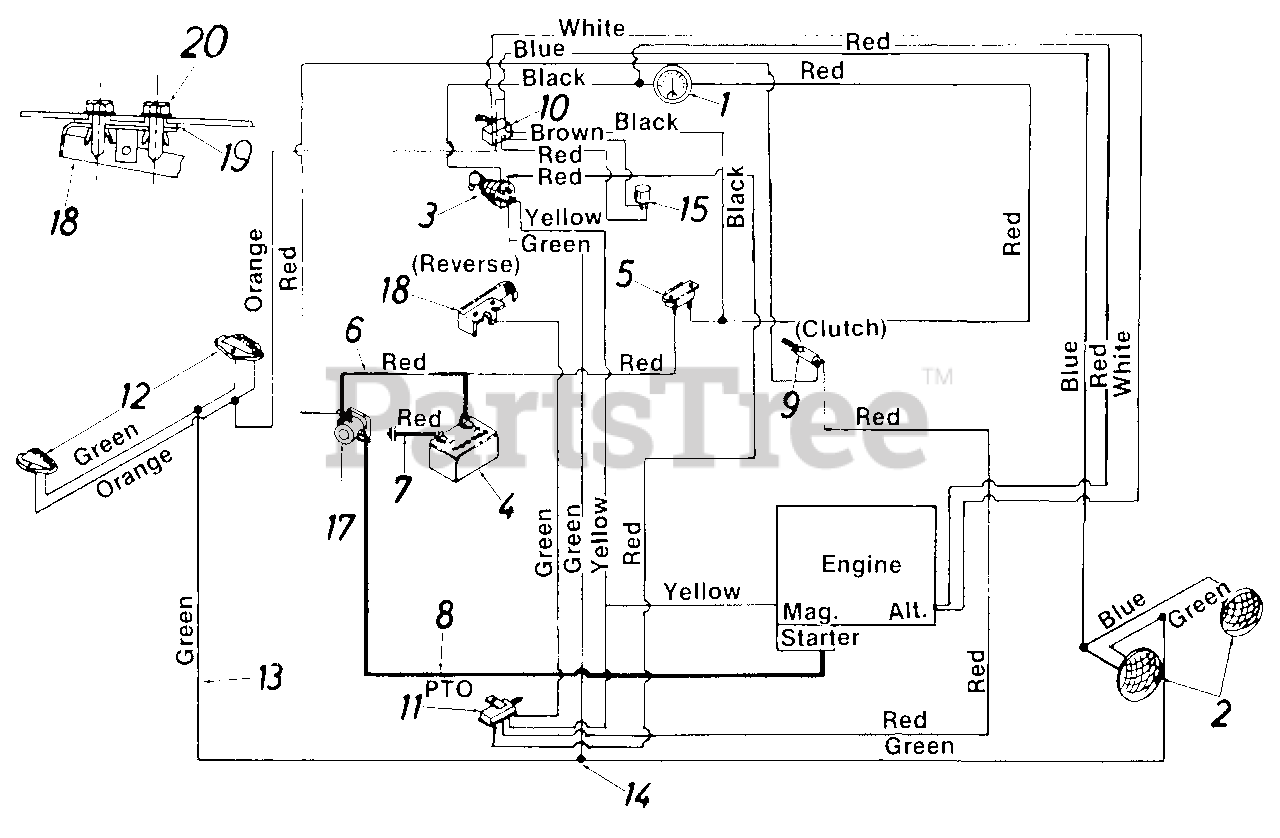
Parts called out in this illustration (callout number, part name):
1	Ammeter
2	HeadLight
3	Ignition Switch
4	Battery
5	Circuit Breaker
6	Electric Wire
7	Electric Wire
8	Electric Wire
9	Safety Switch (Clutch)
10	Light Switch
11	Safety Switch (PTO)
12	Taillight
13	Taillight Lead
14	Adapter Terminal
15	Flasher
17	Solenoid
18	Spring Switch (Reverse)
19	Insulator Nut Plate
20	Hex Wash. Hd. Tap Scr. #8 x 1/2 " Lg.
